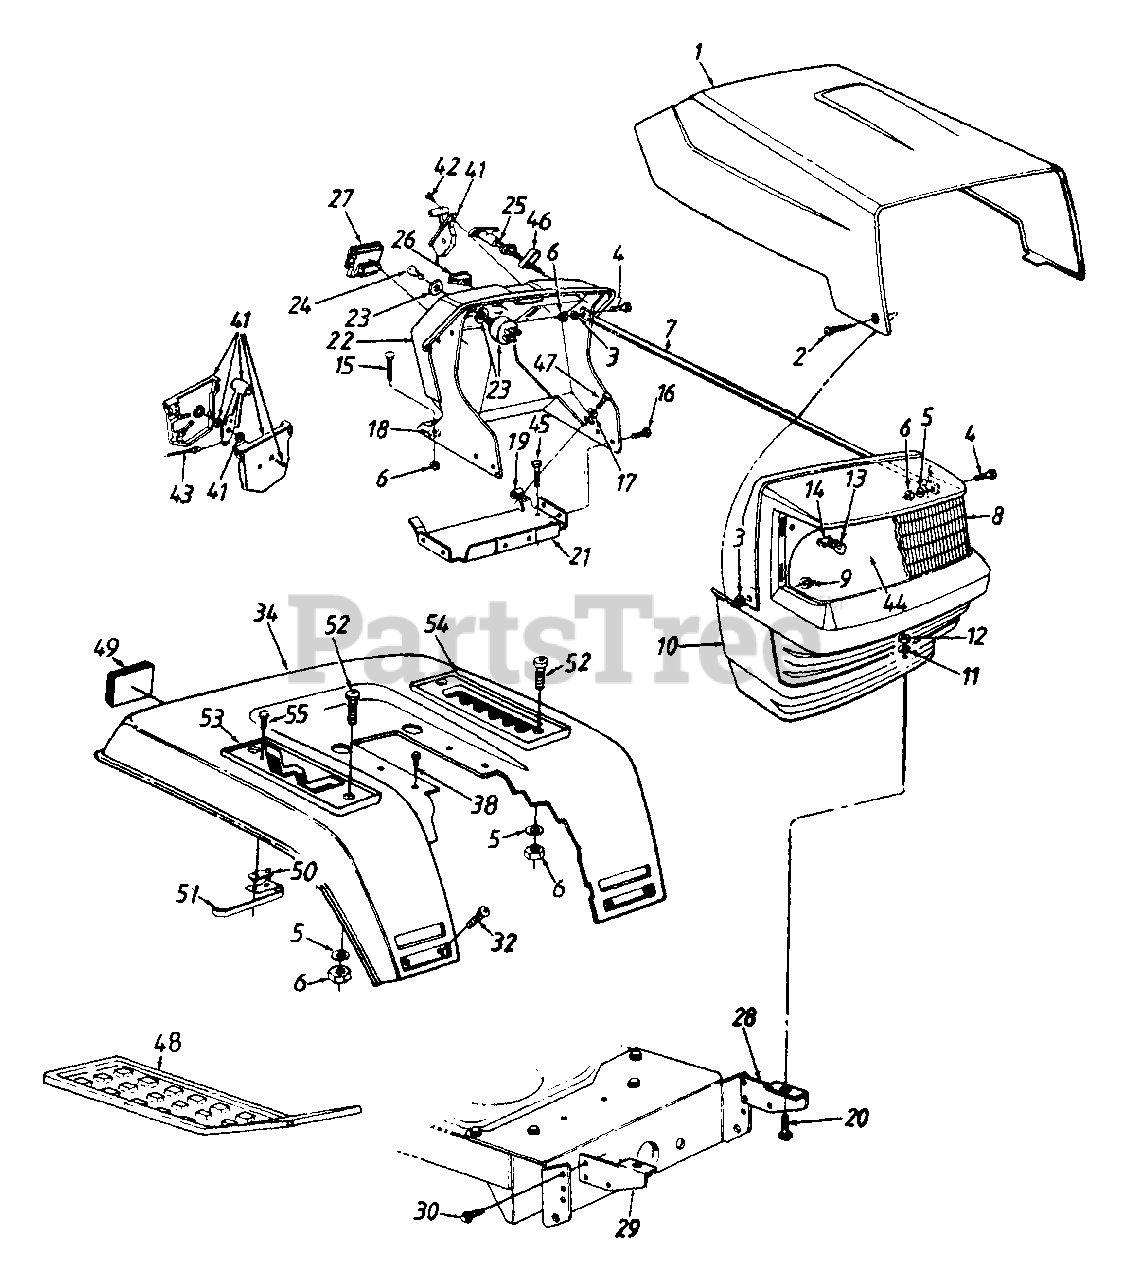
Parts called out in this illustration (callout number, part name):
3	Fl-Wash..28" I.D. x .75" O.D.
4	Hex Bolt 1/4-20 x .62" Lg.
5	L-Wash. 1/4" I.D.
6	Hex Nut 1/4-20 Thd.
8	Headlight Lens
9	Flange L-Nut 1/4-28 Thd.
10	Grille
11	L-Wash. 5/16" I.D.
12	Hex Nut 5/16-18 Thd.
13	Lamp
14	Socket
15	Carriage Bolt 1/4-20 x .75" Lg.
16	Hex Wash. Hd. TT-Tap Scr. 1/4-20 x .5" Lg.
17	Fl-Wash..281" I.D. x .73" O.D.
18	Bolt Retainer 1/4" I.D.
19	Speed Nut 1/4-20 Thd.
20	Hex Bolt 5/16-18 x .75" Lg.
21	Gas Tank Support Brkt.
22	Dash w/Ammeter Hole
23	Ignition Switch
24	Ignition Key
25	Choke Control
26	Light Switch
27	Ammeter
28	Grille Mtg. Brkt.- L.H.
32	Truss Mach. Scr. 1/4-20 x .5" Lg
41	Throttle Box Ass'y.
42	Truss Mach. AB- Tap Scr. 5/16-18 x .5" Lg.
43	Throttle Control Wire
44	Grille Reflector Label
45	Hex Wash. Hd. B-Tap Scr. 5/16-18 x .5" Lg.
46	Choke Retainer
47	Hex TT-Tap Scr. 1/4-20 x .75" Lg.
48	Rubber Foot Pad - L.H.
49	Reflector
50	Insulator Nut Plate
51	Reverse Safety Switch
52	Truss Mach. Scr. 1/4-20 x .75" Lg.
53	Forward/Reverse Index Brkt.
54	7-Speed Index Brkt.
55	Hex Wash. Hd. AB-Tap Scr. #8 x .5" Lg.
